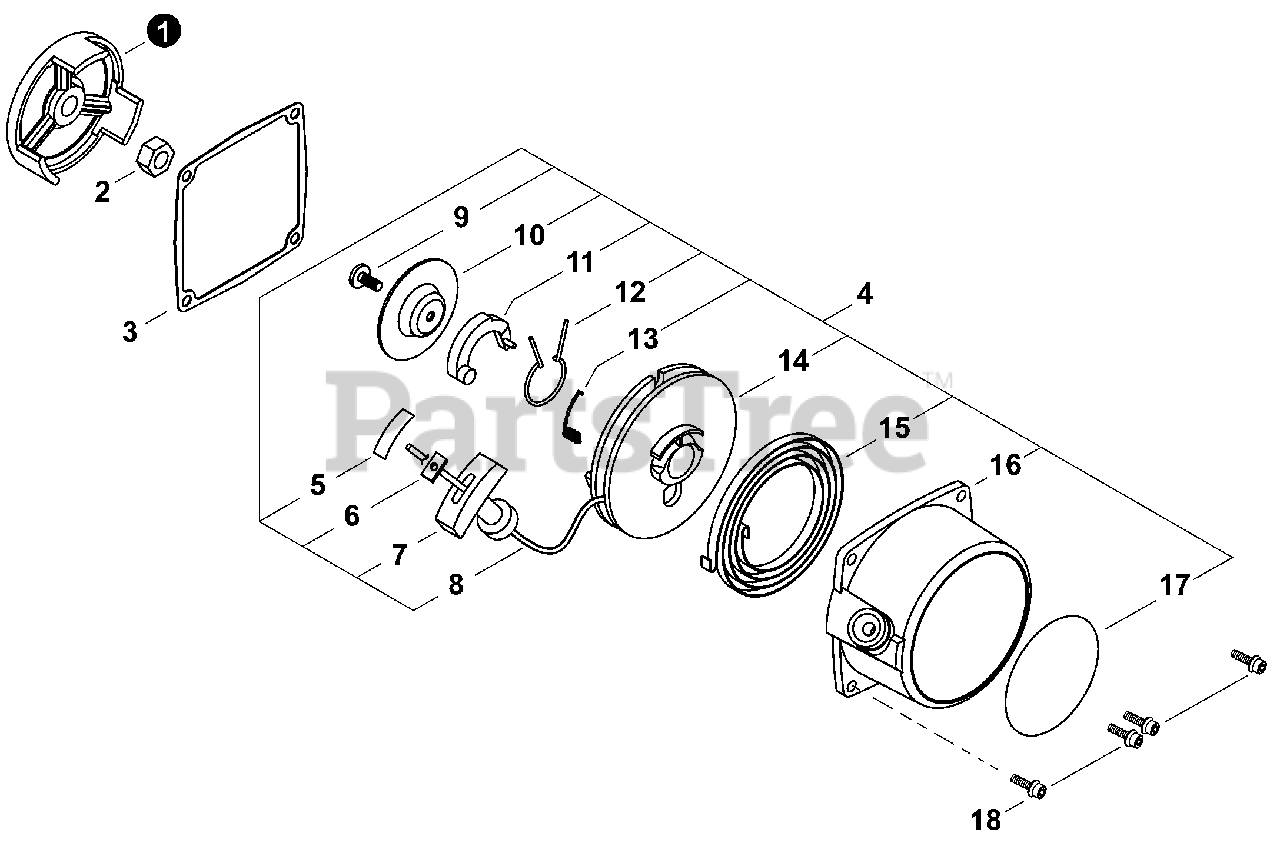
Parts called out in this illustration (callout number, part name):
1	PULLEY, STARTER
2	NUT M8xH5
3	GASKET, RECOIL STARTER
4	STARTER ASSY, RECOIL
5	TAPE
6	RETAINER, ROPE
7	GRIP, STARTER
8	ROPE, STARTER
9	SCREW
10	PLATE, FRICTION
11	RATCHET
12	SPRING, FRICTION
13	SPRING, RETURN
14	REEL, ROPE
15	SPRING, RECOIL
16	CASE, RECOIL STARTER
17	LABEL - RECOIL STARTER
18	BOLT M4x16
